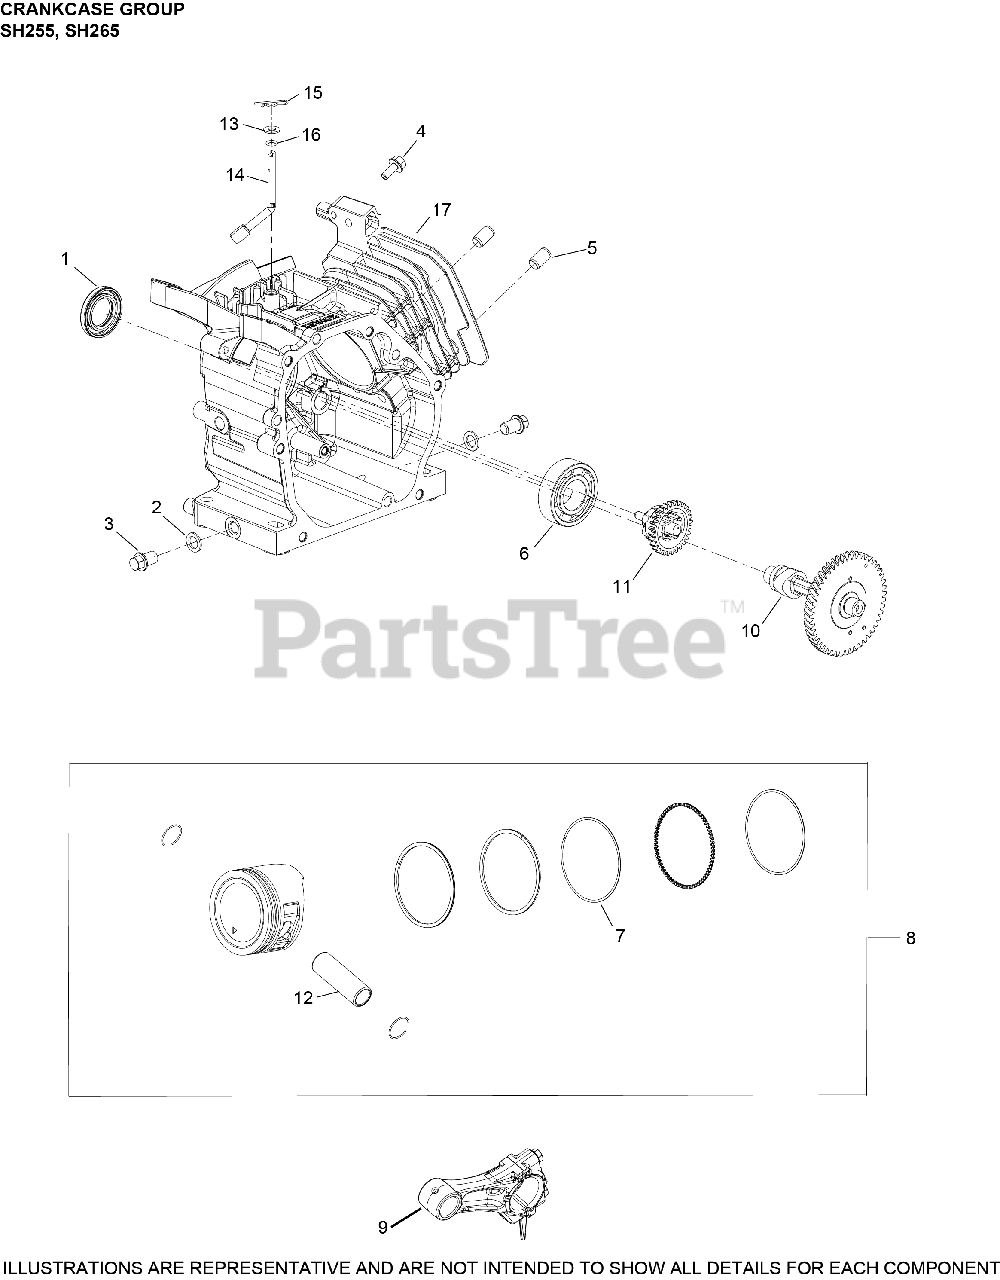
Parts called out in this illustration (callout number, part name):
1	SEAL- USE 17 032 29-S
2	WASHER, DRAIN PLUG
3	KIT, DRAIN PLUG
5	DOWEL, CYLINDER HEAD-(#1438013S)
6	BEARING, BALL
8	KIT, PISTON (STD)
9	ROD, CONNECTING ASSEMBLY
12	PIN, PISTON
13	WASHER, FLAT (DIA 13MM O.D.)
14	CROSS SHAFT
15	CLIP, GOVERNOR SHAFT
17	CRANKCASE
